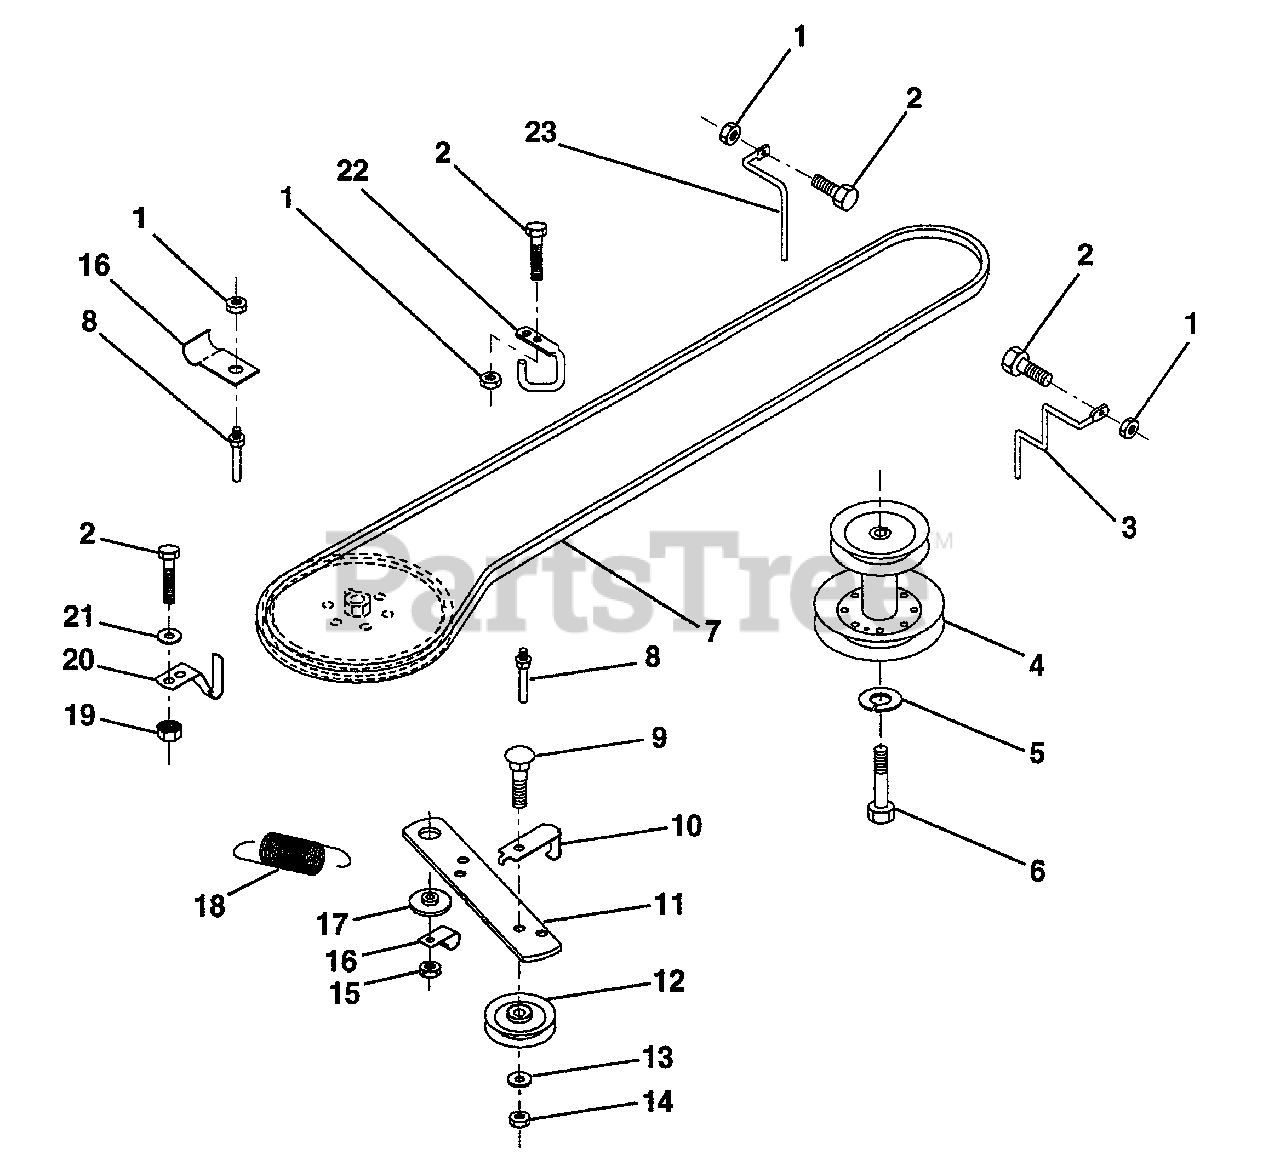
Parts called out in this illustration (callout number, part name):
1	Nut, Crownlock 5/16-18
2	Bolt, Hex Hd 5/16-18 UNC x 3/4
3	Keeper,Mower Drive, R. H.
4	Pulley, Engine
5	Washer, Lock 7/16
6	Bolt, Fin Hex 7/16-20
7	Traction, V-Belt Drive
8	Keeper, T/A Ground Drive Belt
9	Bolt, Carr. 3/8-16 UNC x 1-1/2
10	Keeper, Belt Ground Drive Idler
11	Arm, Ground Drive Clutch
12	Idler, Flat
13	Washer 13/32 x 13/16 x 16 Ga.
14	Nut, Centerlock 3/8-16 UNC
15	Nut, Crownlock 3/8-16 UNC
16	Clip, Insulated
17	Spacer, Retainer
18	Spring Extension
19	Nut, Keps 5/16-18 UNC
20	Keeper, T/A Ground Drive Belt
21	Washer 11/32 x 5/8 x 16 Ga.
22	Keeper, Frame Ground Drive Belt
23	Keeper, Mower Drive, L. H.
